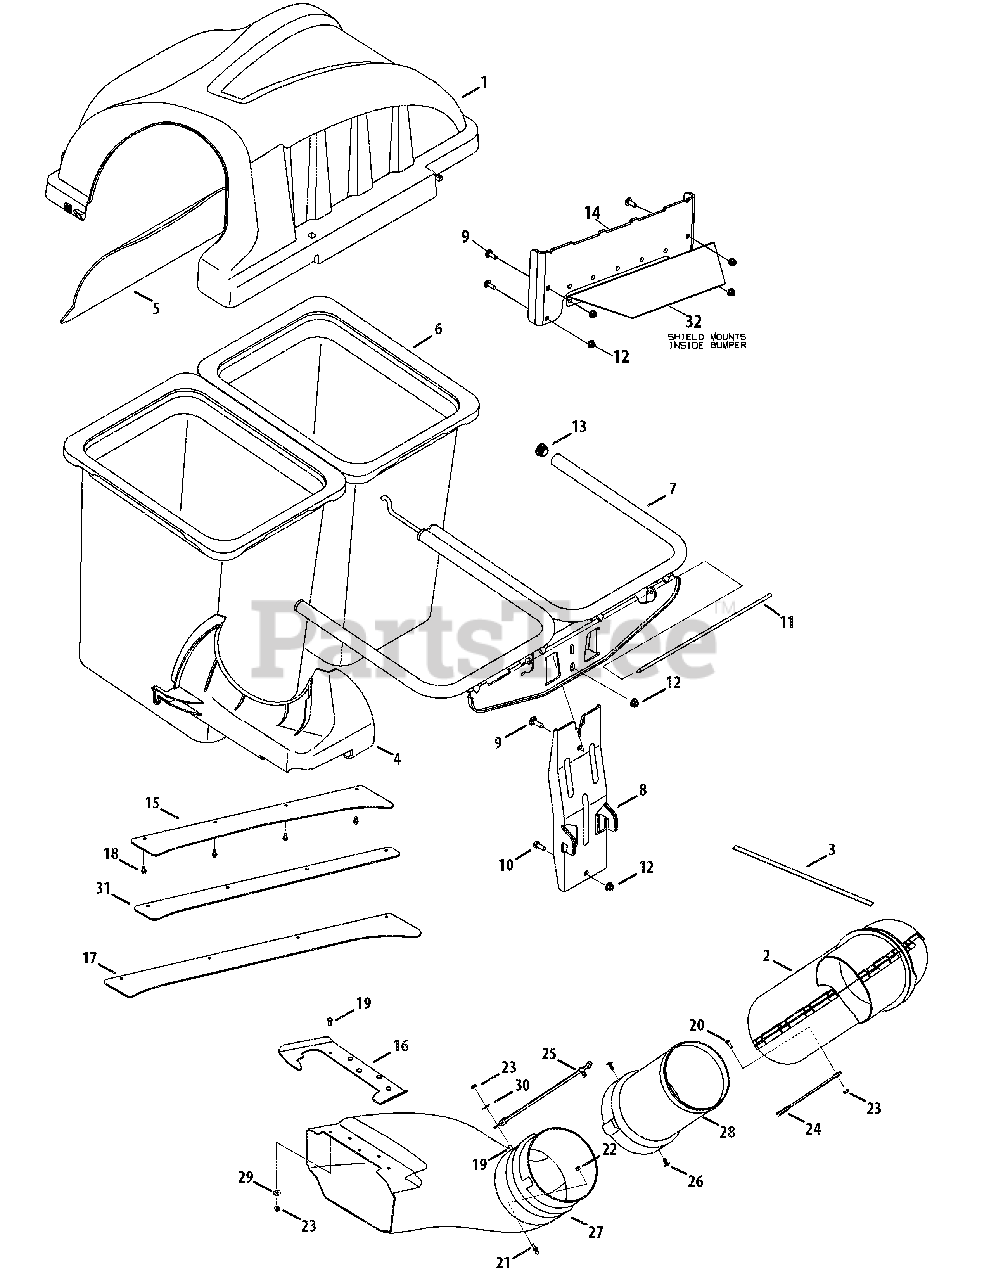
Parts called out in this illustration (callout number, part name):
1	Cover Assembly, Bag, Double
2	Chute Assembly, Bagger, Upper, 32in
3	Foam, Tape, .75 Wide X .125 Thick
4	Support, Bagger, Upper Chute
5	Screen, Bagger
6	Bag Assembly, Grass bag, Cub
7	Support Assembly, Bag, Double
8	Bracket Assembly, Bagger, Vert Support
9	Screw, Carriage, 5/16-18, 1.00
10	Hex Head Screw, 5/16-18, .75, Gr5, Std
11	Pin, Cover Hinge, Bagger, Double
12	Nut, Flange lock, 5/16-18, Nylon
14	Bracket, Bagger
18	Screw, Tap, 1/4-20, 0.500, Hex ind washer
19	Hex Head Screw, 1/4-20, .620, Gr5, Std
20	Screw, Mach, 1/4-20, 0.750
21	Pin, Grass catcher, 1/4-20
22	Nut, Hex Lock, 1/4-20, Gr8, Nylon
23	Nut, Flange Lock, 1/4-20
24	Strap, Chute, 11.65 Lg
25	Strap, Chute
26	Clip, Ratchet, .250 Dia
27	Chute, Elbow
28	Chute, Bagger, Adapter, 8x13.5
29	Wash, Bell, .265 X.75 X .062
30	Wash, Flat, .265x1.0x.030, Ht
31	Baffle, Front
32	Muffler Shield
